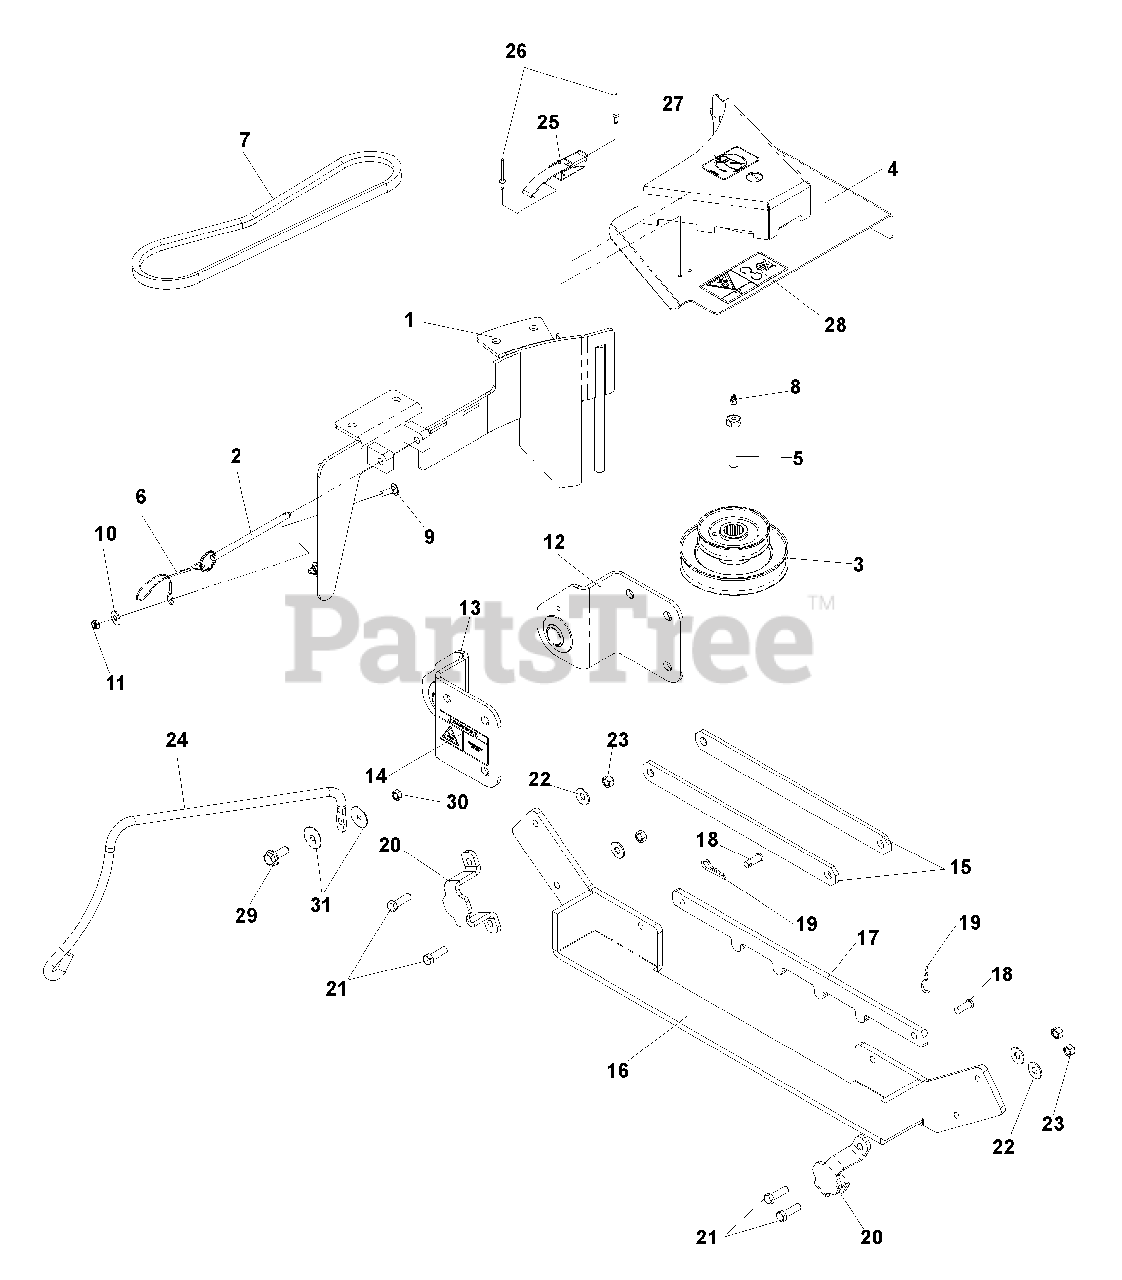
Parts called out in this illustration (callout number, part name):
1	BLOWER DECK PLATE, 52" DECK
1	BLOWER DECK PLATE, 61" DECK
3	STACK PULLEY, 52" DECK
3	STACK PULLEY, 61" DECK
4	BELT SHIELD, 52" DECK
4	BELT SHIELD, 61" DECK
5	HCS, 7/16-20 X 2 1/2, GR8
7	BELT, 52" DECK
7	BELT, 61" DECK
8	ZERK
9	RHSNB, 1/4-20 X 3/4, GR2
10	WASHER, 1/4
11	NUT, 1/4-20, JAM, NYLOC
12	HITCH BRACKET, LEFT
13	HITCH BRACKET, RIGHT
14	DECAL, HOT SURFACE
16	WEIGHT BAR
17	HOLD DOWN, WEIGHT BAR
18	CLEVIS PIN
19	SPRING RETAINER
20	WEIGHT KEEPER
21	HCS, 3/8-16 X 1 1/4, GR5
22	WASHER, 3/8
23	NUT, 3/8-16, NYLOC
24	HOSE SUPPORT
25	DRAW LATCH
26	RIVET, BLIND, 5/32 DIA.
27	DECAL, NO STEP
28	DECAL, DANGER BELT DRIVES
29	HCS, 5/16-18 X 1 1/4, GR5
30	NUT, 5/16-18, NYLOC
31	WASHER, 5/16
